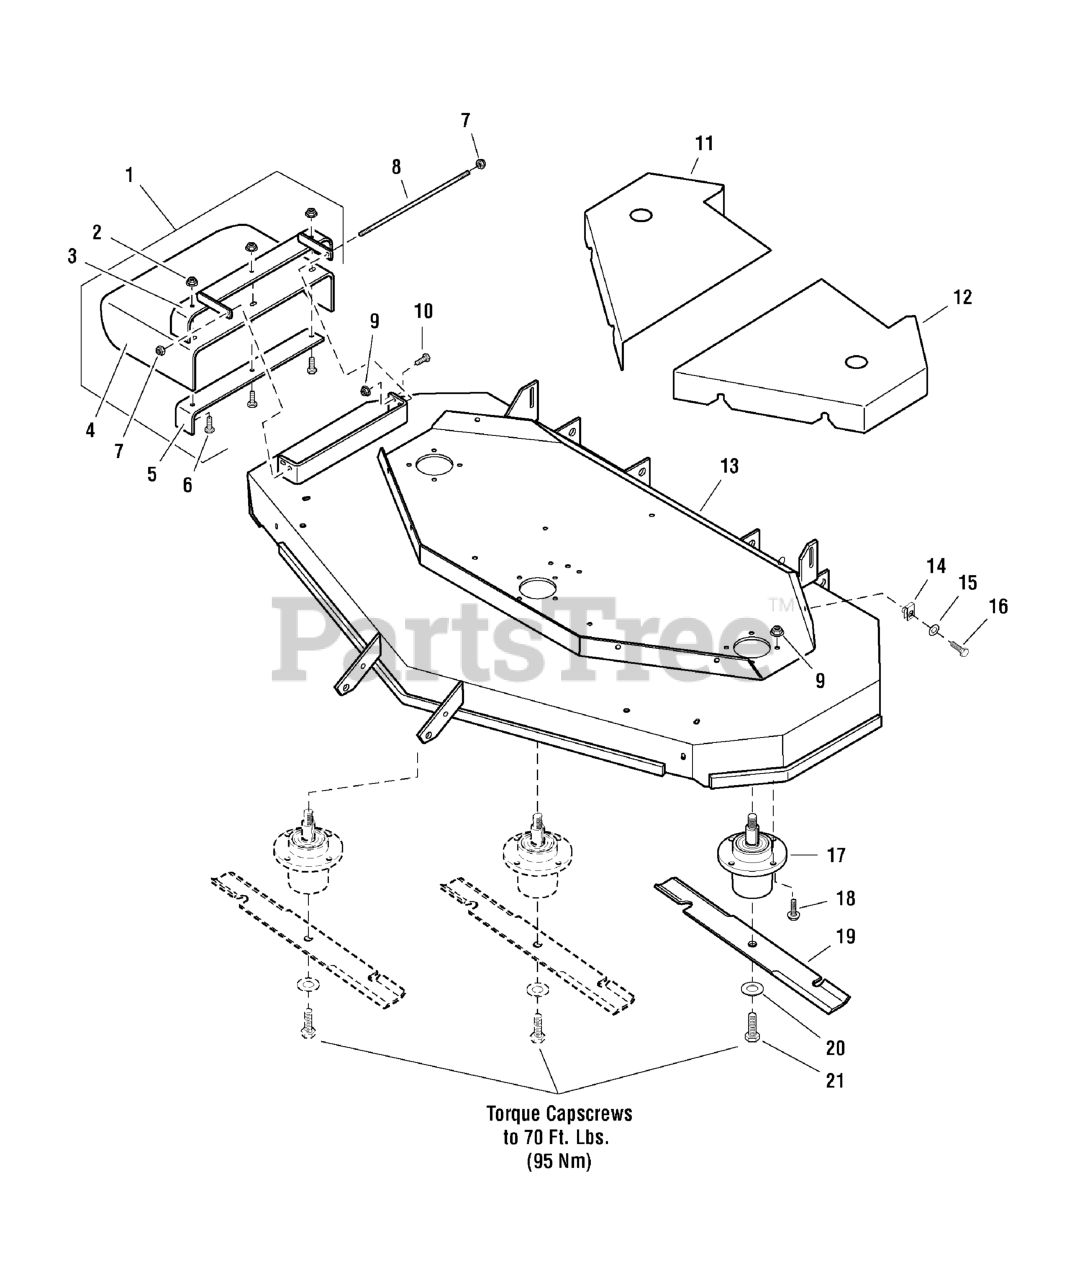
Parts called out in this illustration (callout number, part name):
1	61" RUBBER CHUTE ASSEMBLY, Complete
2	NUT, 3/8-16 Hex Nylock Flange
3	CHUTE FRAME
4	RUBBER CHUTE
5	CHUTE SUPPORT
6	BOLT, 3/8-16 X 1-1/4" GD5 CZ
7	NUT, 5/16-24 HEX NYLON LOCK
8	CHUTE MOUNT ROD
9	NUT, 5/16-18 Hex Nylock Flange
10	BOLT, 5/16-18 X 3/4 GD5
11	SPINDLE COVER - RH
12	SPINDLE COVER - LH
13	DECK SHELL W/DECALS, 61"
14	BODY CLIP, 5/16-18-7GA MATERIAL
15	WASHER, 5/16" SAE
16	BOLT, 5/16-18 X 3/4 GD5
17	ASSM, SPINDLE, LOW PROFILE
18	BOLT, Flange Head, 5/16-18 x 1-1/4
19	MOWER BLADE, 21"
20	WASHER, 5/8" GRADE 8, YZ
21	BOLT, 5/8-11 X 1-3/4 GD8
